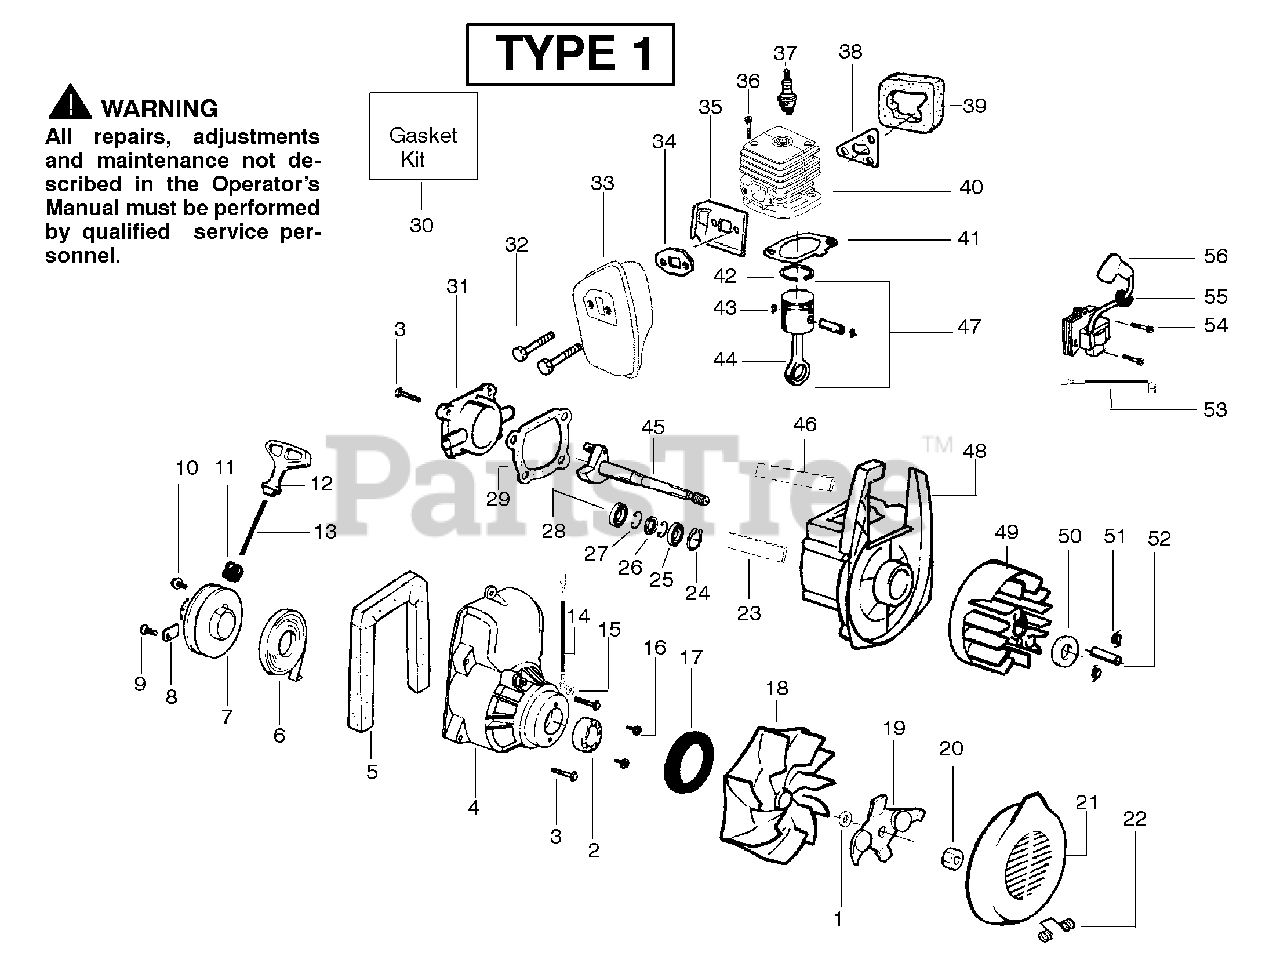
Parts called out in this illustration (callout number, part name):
1	Washer-Belleville
3	Screw
4	Fan Housing Ass'y.
5	Foam Seal
6	Starter Spring
7	Starter Pulley Kit
8	Retainer Can
10	Screw-Starter Pulley
11	Eyelet - Flange
12	Starter Handle
13	Kit - Rope
14	Leadwire - Ground
18	Assy.Impeller
19	Assy. Mulch Blade
21	Door - Inlet
22	Spring-Return Cover
23	Foam - Side
24	Retainer Ring-C'chaft
25	Bearing - Outer
26	Seal - Crankcase
27	Retaining Ring- C'case
28	Bearing - Inner
29	Gasket - C'case/Shrd
30	Kit - Gasket
31	Cover - Crankcase
32	Bolt - Muffler
33	Assy. -Muffler
34	Gasket - Muffler
35	Shield - Muffler
37	Spark Plug (RCJ-8Y)
38	Gasket- Carb. Adapter
40	Cylinder Kit
41	Gasket - Cylinder
42	Piston Rings (2)
43	Retainer
44	Connecting Rod Ass'y.
45	Assy. - Crankshaft
46	Foam - Top
47	Piston Kit
48	Assy.- Crankcase
49	Assy-Flywheel
51	Spring-Starter Dog
52	Flywheel Spacer
53	Leadwire - Switch
55	Grommet-Ign. Module
56	Ignition Module
